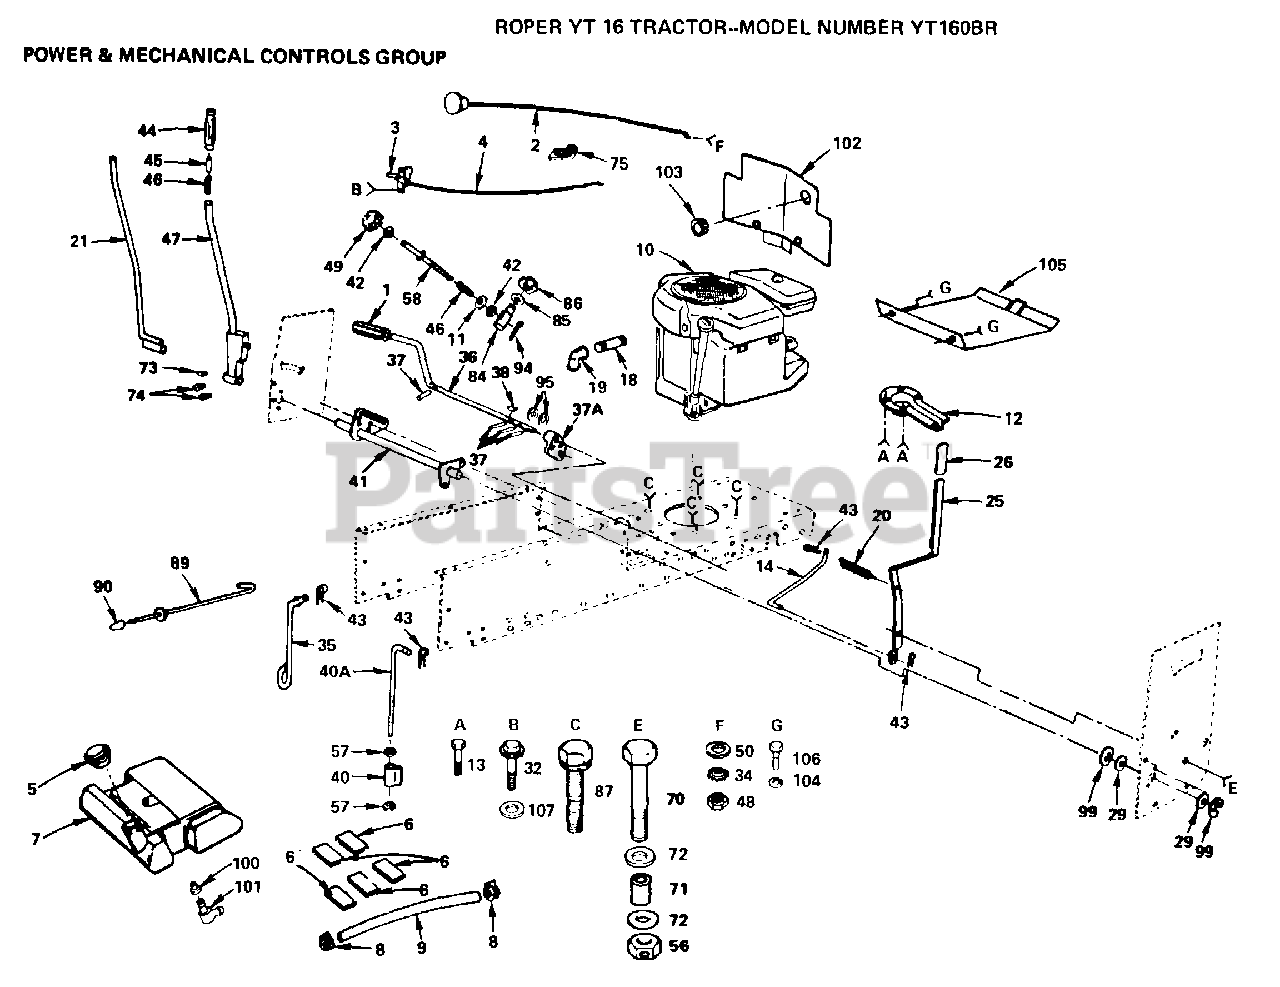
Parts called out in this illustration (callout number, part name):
1	PEDAL COVER T
4	THROTTLE CONTROL
6	PAD-SPACER T
10	ENGINE, B&S
11	WASHER
18	PIPE NIPPLE LT
19	ELBOW
20	"SPRING.EXT.8.5"""
21	ROD ASSY-LEVER LT
25	HANDLE-CLUTCH L
29	WASHER
32	SCREW LT
34	LOCKWASHER
41	SHAFT ASSY YTV
42	NUT
44	HANDLE GRIP T
46	SPRING T
47	LEVER ASSY LT
50	WASHER
57	NUT.HEX.3/8-16UNC
58	ROD ADJUST LT
71	BUSHING LT
85	WASHER
86	KLIP RING
87	SCREW
90	PLUNGER CAP T
99	RING
100	BUSHING OUTLET T
101	FUEL TANK STEM GT
103	SNAP BUSHING T
104	LOCKWASHER
106	BOLT
107	WASHER
